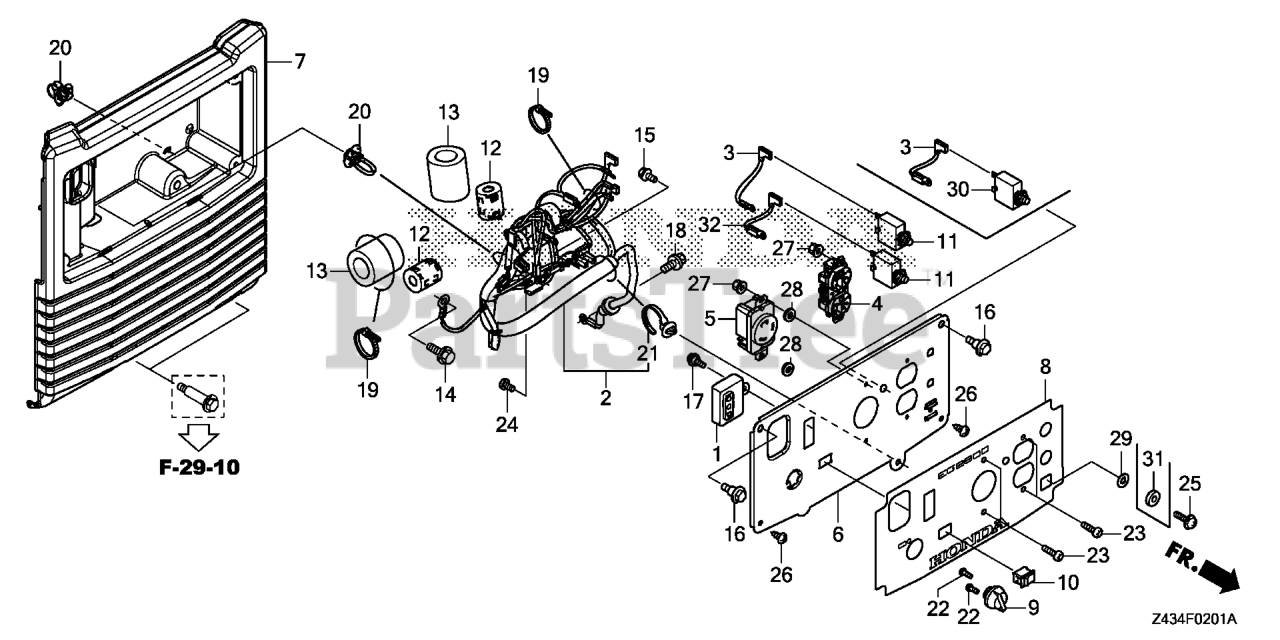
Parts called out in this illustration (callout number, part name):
1	IGNITION UNIT
2	WIRE HARNESS ASSY., CONTROL
3	WIRE, TERMINAL (150MM)
4	RECEPTACLE (20A/125V)
5	RECEPTACLE (30A/125V)
6	PANEL, CONTROL
7	CASE, CONTROL PANEL *R280* (POWER RED)
8	MARK, CONTROL PANEL
9	SWITCH ASSY., ENGINE STOP
10	SWITCH, AUTO THROTTLE
11	PROTECTOR, CIRCUIT (20A) (WHITE)
12	FILTER, SUB NOISE (AC)
13	SUPPORTER, FILTER
14	BOLT, FLANGE (6X14)
15	SCREW, TAPPING (5X12)
16	BOLT, CONTROL PANEL
17	SCREW, PAN (5X13)
18	BOLT, GROUND (6X12) (SN)
19	TIE, CABLE
20	CLIP, WIRE HARNESS
21	CLIP, HARNESS BAND (145MM) (BLACK)
22	SCREW, PAN (3X8)
23	SCREW, PAN (4X10)
24	SCREW, PAN (5X8)
25	SCREW, PAN (5X16)
26	SCREW, TAPPING (5X12)
27	NUT, FLANGE (4MM)
28	WASHER, PLAIN (4MM)
29	WASHER, PLAIN (5MM)
32	WIRE, TERMINAL (150MM)
